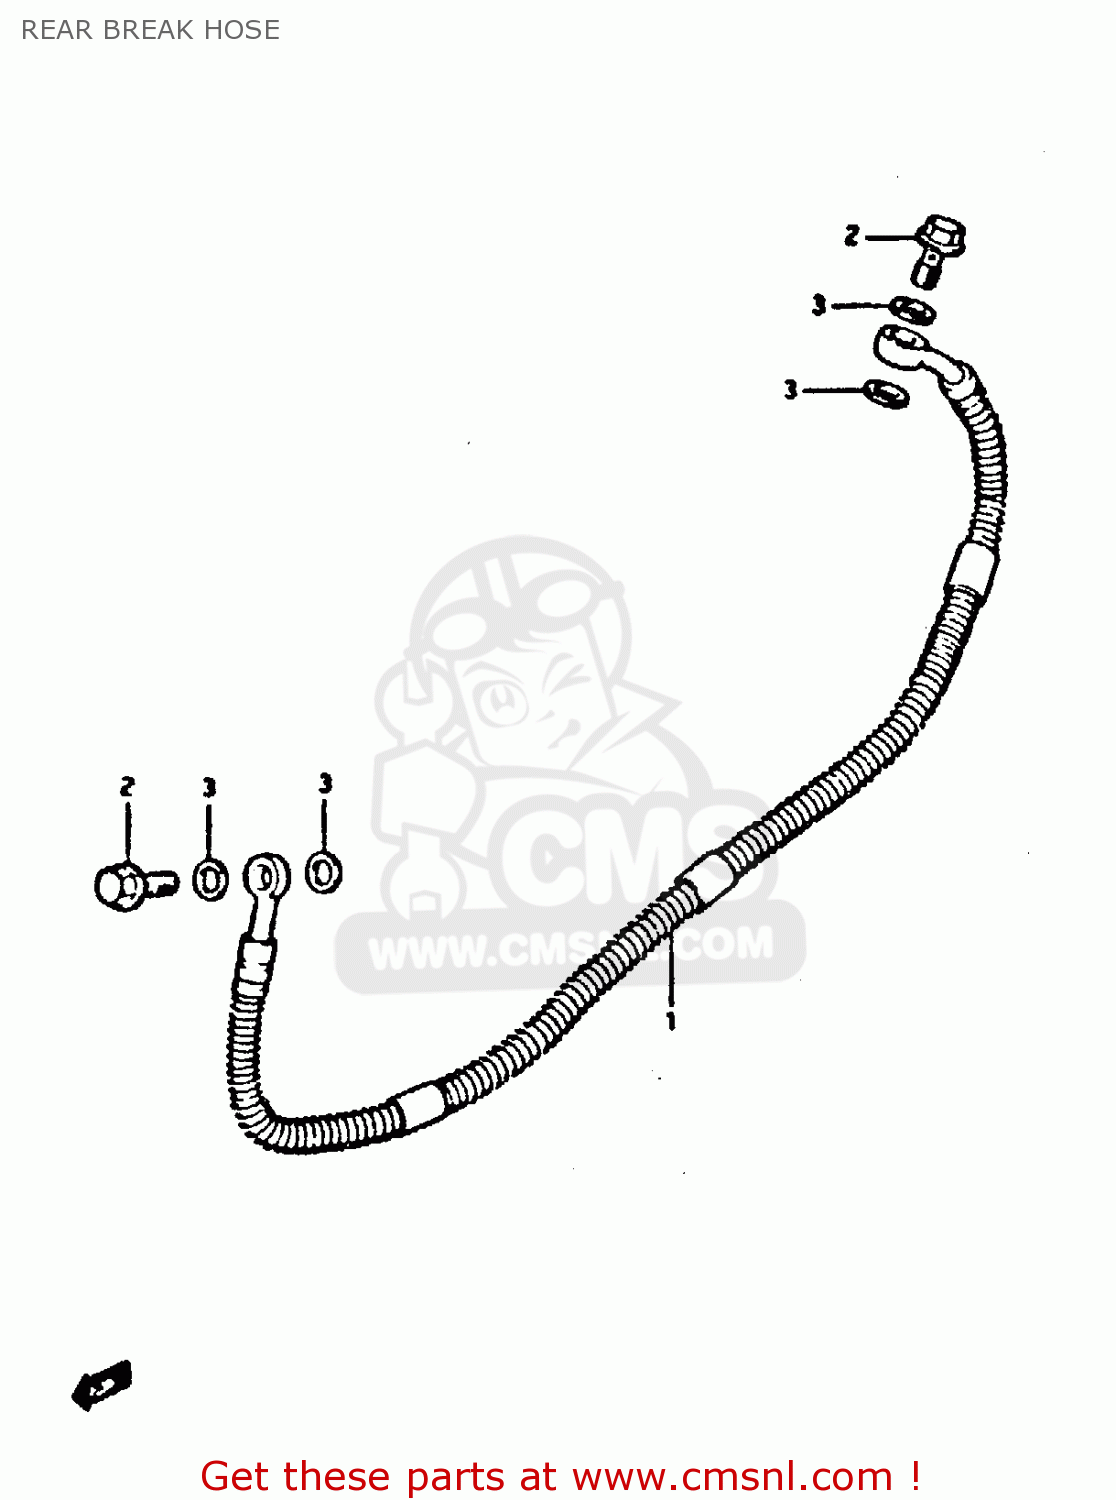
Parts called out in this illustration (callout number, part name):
1	HOSE,REAR BRAKE
2	BOLT,UNION
3	WASHER
